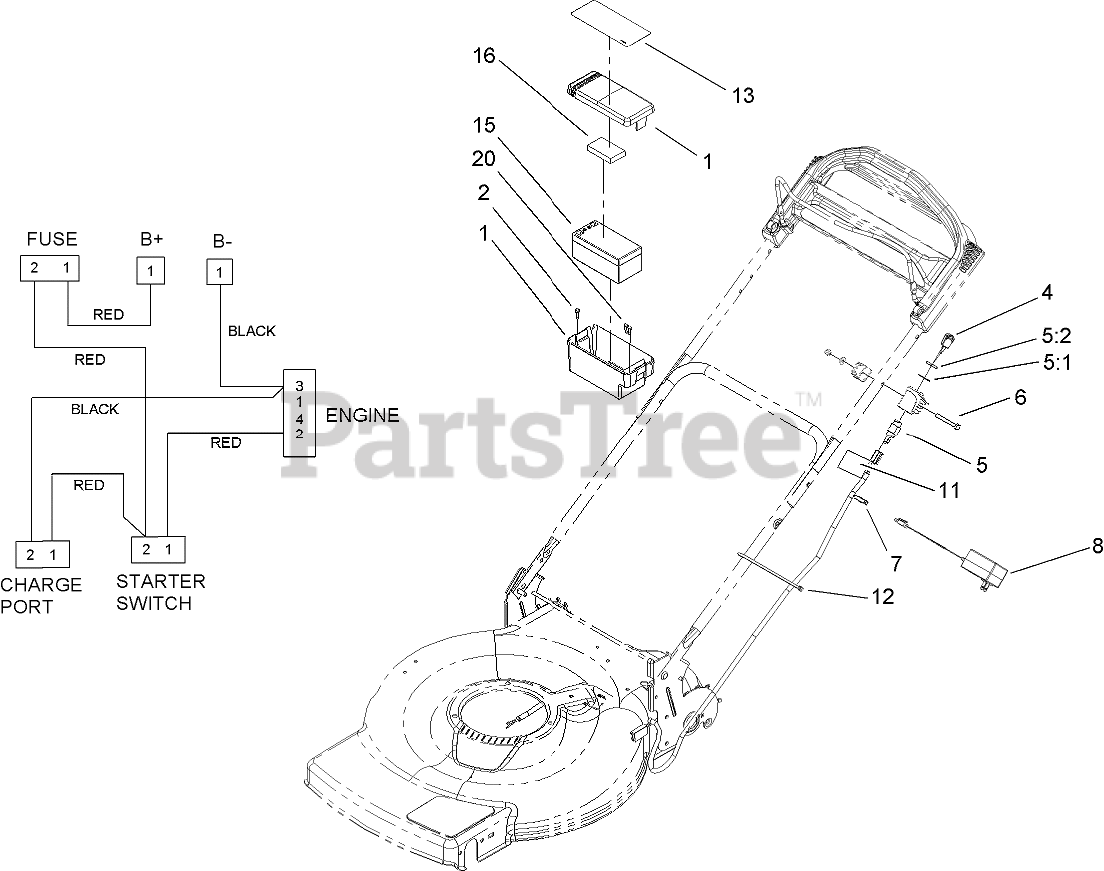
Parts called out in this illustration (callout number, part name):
1	BATTERY BOX ASM
2	SCREW-FORMING, THREAD
5	STARTER SWITCH ASM
5:1	WASHER-TOOTH, INTERNAL
5:2	NUT-HH
6	MOUNT-SWITCH
7	HARNESS-WIRE
8	CHARGER-12 VOLT
11	DECAL-WARNING
12	TIE-CABLE
13	DECAL-INSTRUCTIONAL
15	BATTERY-WET
16	FOAM-BATTERY, TOP
20	FUSE-40 AMP
